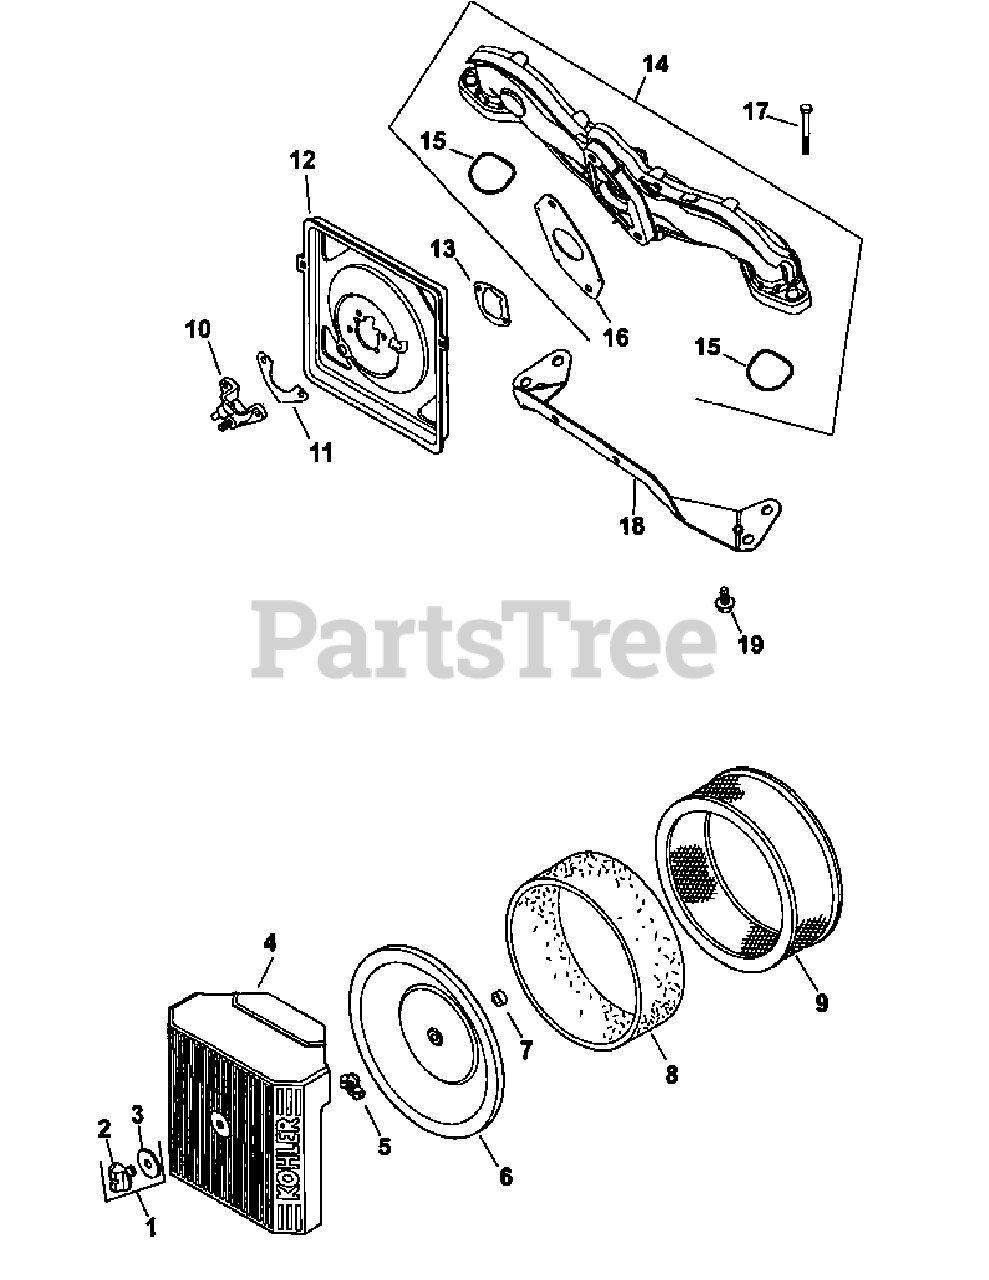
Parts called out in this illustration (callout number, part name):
1	Knob With Seal Kit
4	Air Cleaner Cover
6	Inner Air Cleaner Cover
7	Inner Air Cleaner Seal
8	Precleaner Element
9	Air Filter & Precleaner Elements
10	Spit Back Cup
11	Spit Back Cup Gasket
12	Air Cleaner Base
13	Air Cleaner Gasket
14	Intake Manifold
15	Intake Port O-Ring
16	Carburetor Gasket
17	Hex Flange Screw (M6 x 1.0 x 40)
18	Air Cleaner Bracket
19	Hex Flange Screw (M5 x .8 x 10)
